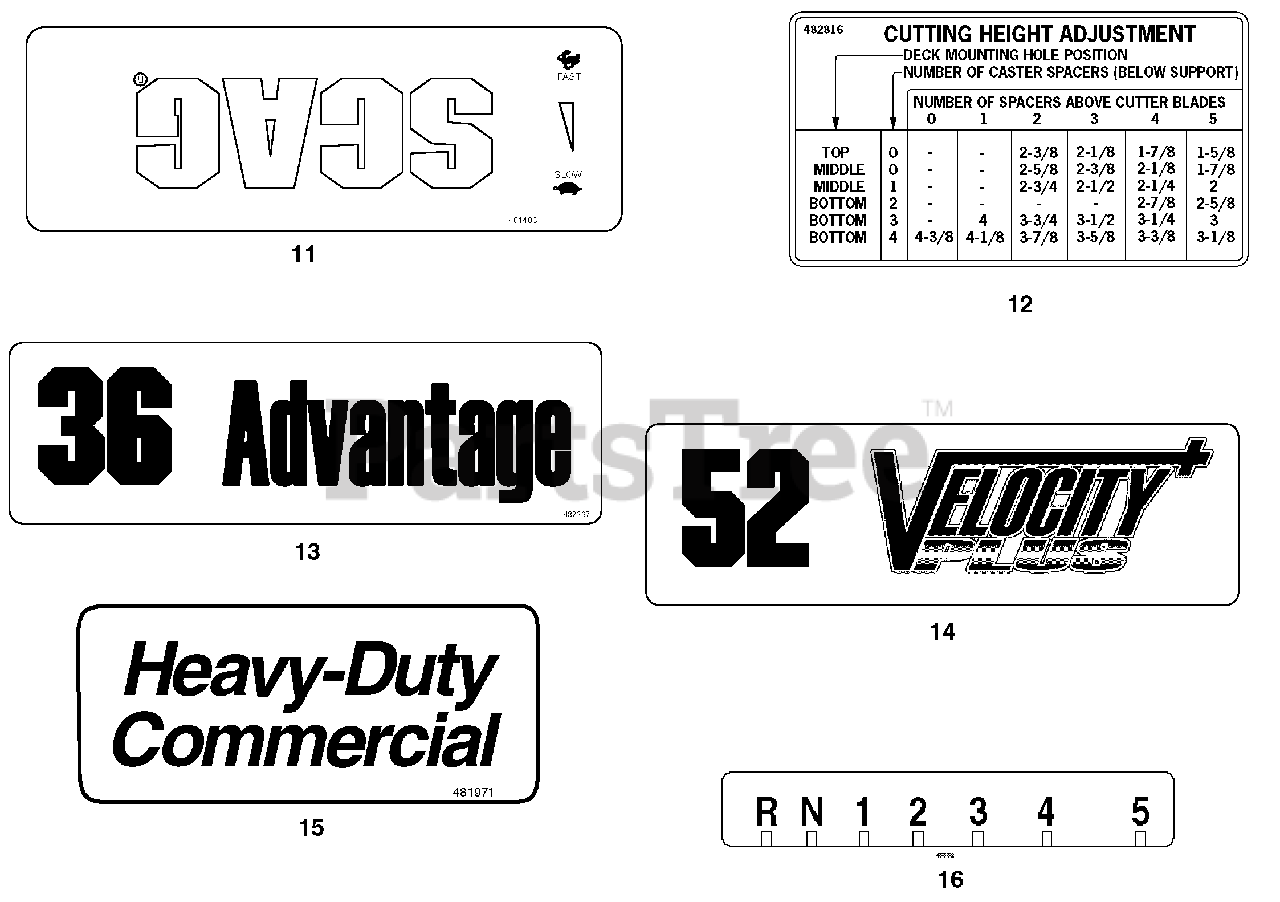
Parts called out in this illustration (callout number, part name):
11	Decal, Instrument Panel - Front
12	Decal, Height of Cut
13	Decal, 32
14	Decal, 48 Velocity Plus
15	Decal, Heavy Duty Commercial
16	Decal, Shift Index
